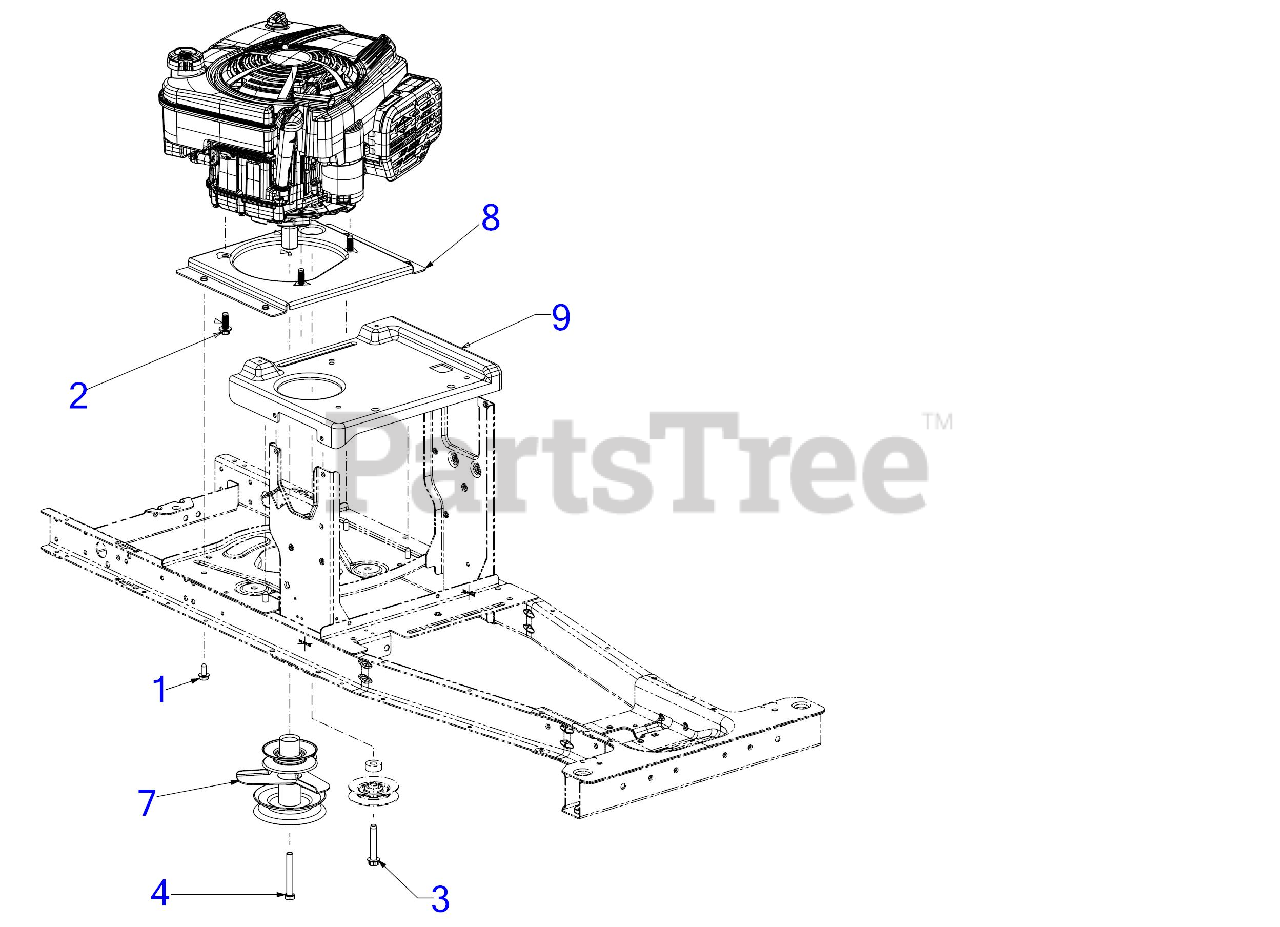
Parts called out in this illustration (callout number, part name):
1	SCREW 5/16-18 x .750
2	SCREW 3/8-16 x 1
3	SCREW 3/8-16 x 2.250
4	SCREW 3/8-24 x 2.75 GR5
7	PULLEY-4.46 DIA/3.39 DIA
8	ENGINE PLATE MOUNT
9	SEAT PLATE 24"
